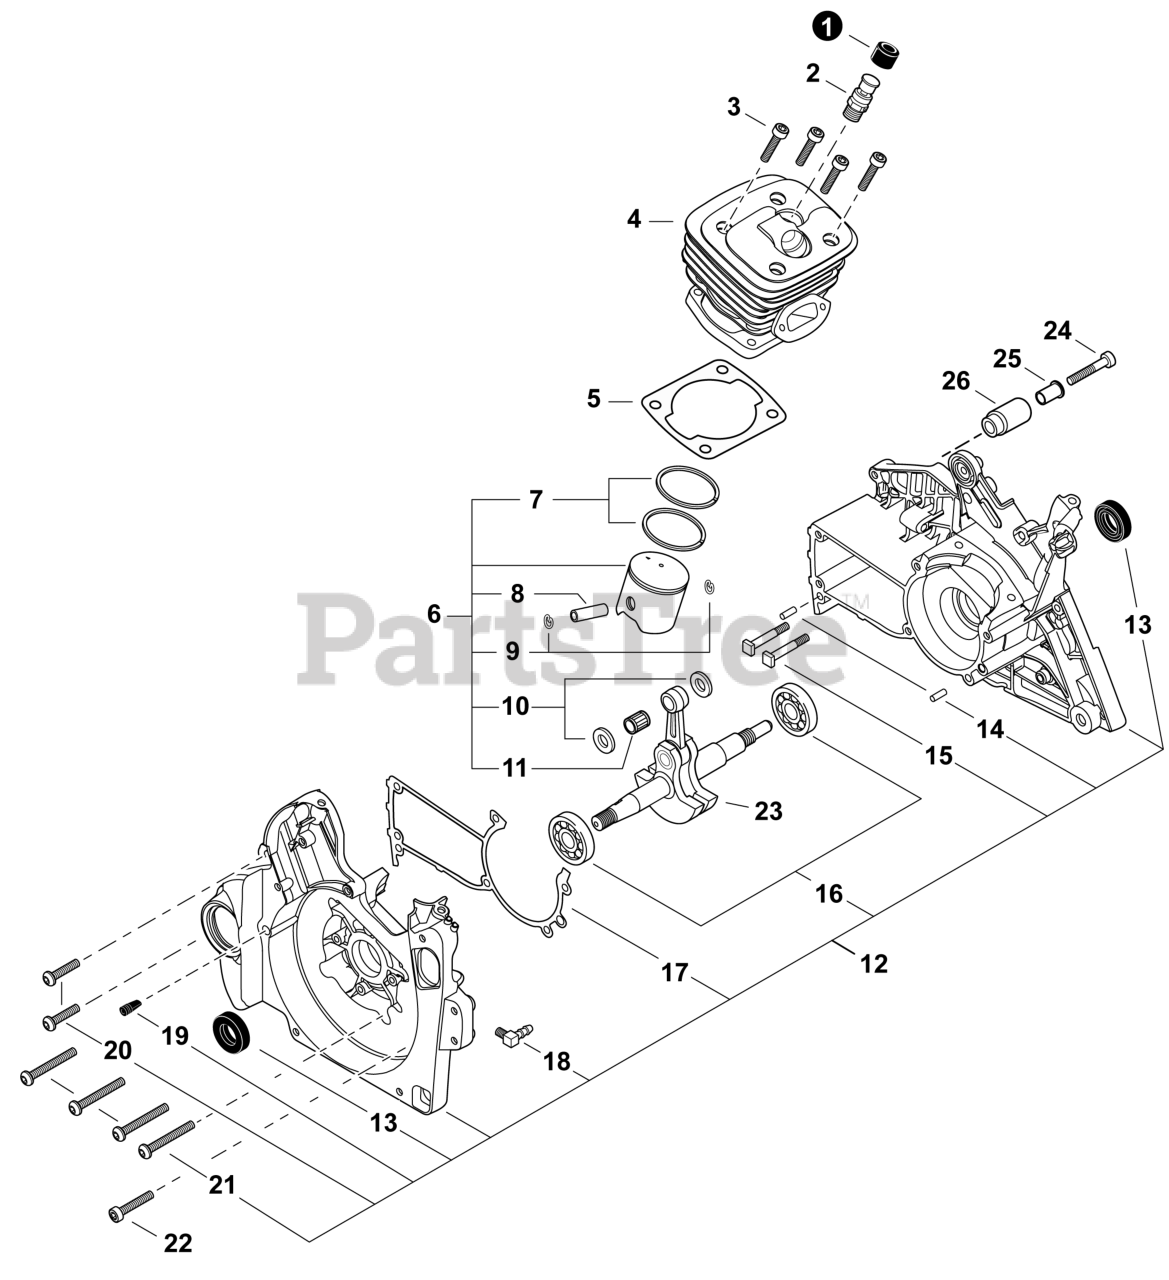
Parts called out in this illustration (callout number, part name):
1	COVER, DUST
2	VALVE ASSY, DECOMPRESSION
3	BOLT, TORX 5x25
4	CYLINDER
5	GASKET, CYLINDER
6	PISTON KIT
7	RING, PISTON
8	PIN, PISTON
9	RING, SNAP 11
10	WASHER, THRUST
11	BEARING, NEEDLE 11
12	CRANKCASE KIT
13	SEAL, OIL 15
14	PIN, LOCATING 5x10
15	BOLT, STUD M8x1.25x34.5
16	BEARING, BALL 6202
17	GASKET, CRANKCASE
18	CONNECTOR, PIPE
19	VENT ASSY
20	BOLT, TORX 5x20
21	BOLT, TORX 5x35
22	BOLT, TORX 5x25
23	CRANKSHAFT ASSY
24	BOLT, TORX 5x35
25	COLLAR 5
26	CATCHER, CHAIN
